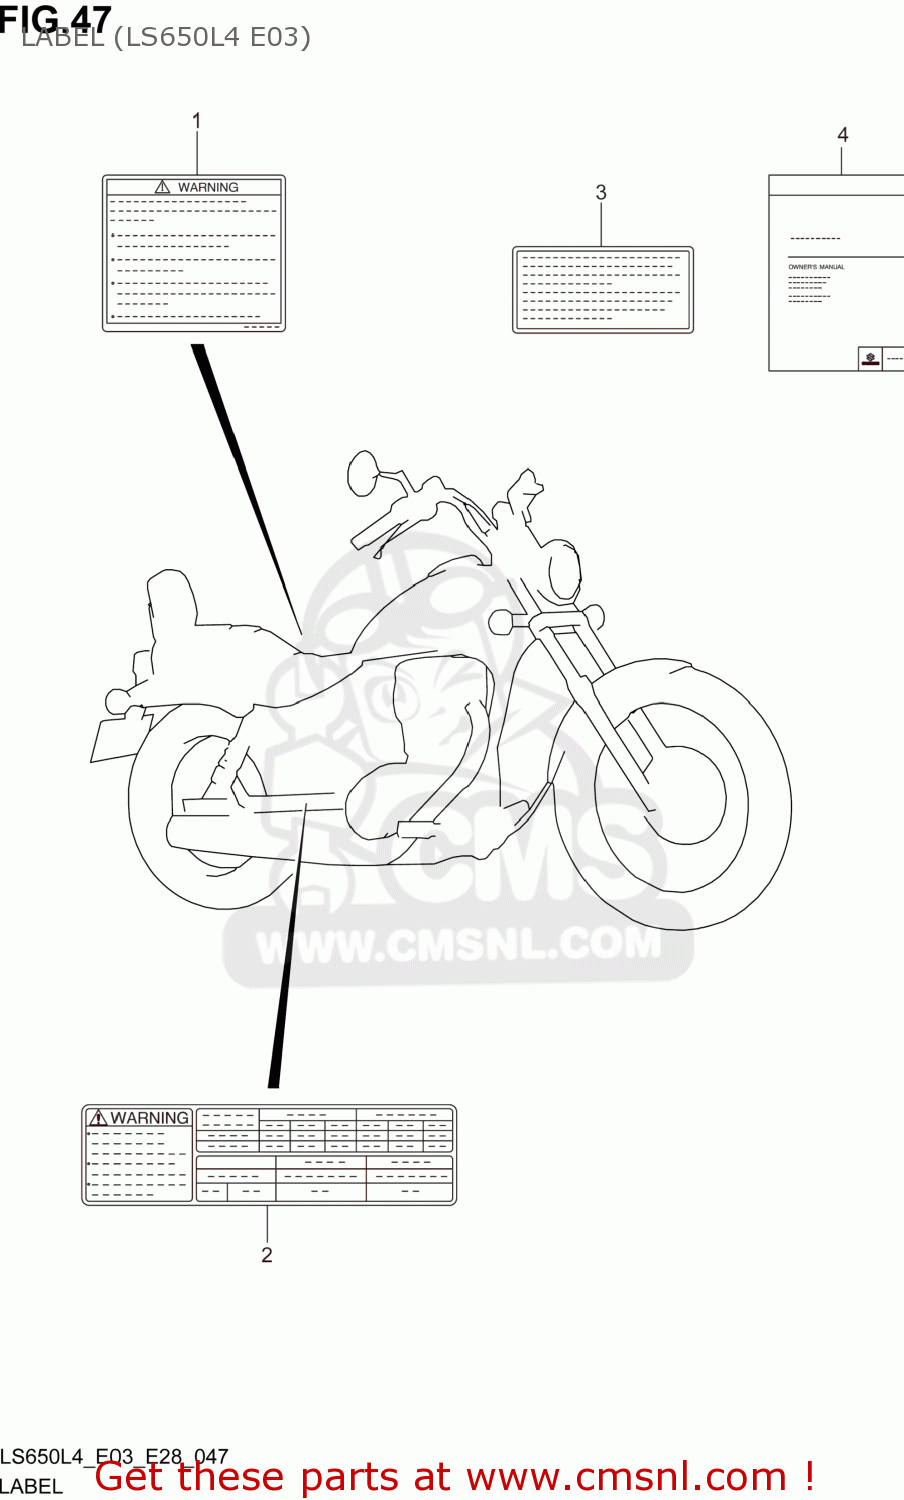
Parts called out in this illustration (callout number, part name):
1	LABEL,GENERAL WARNING
2	LABEL,TIRE INFORMATION
3	LABEL,MANUAL NOTICE
4	MANUAL,OWNER'S
